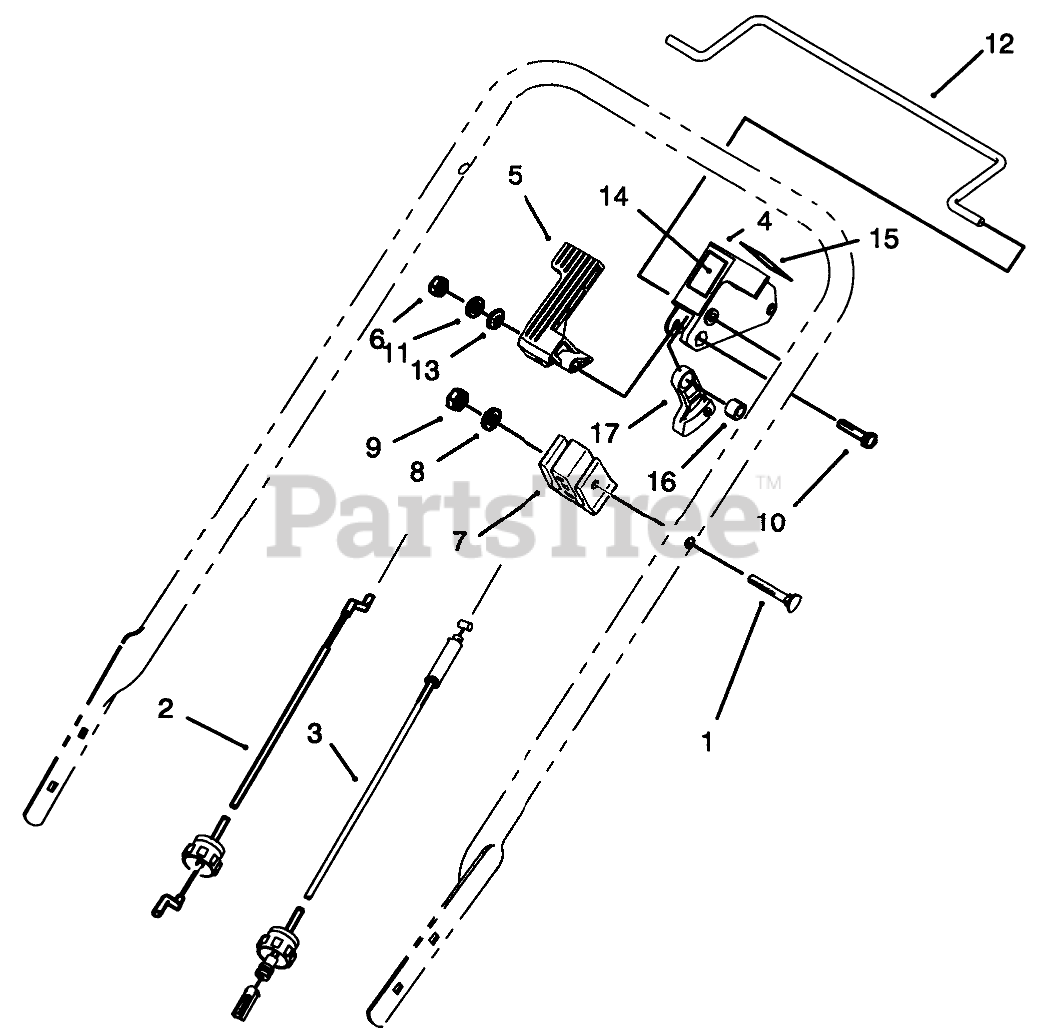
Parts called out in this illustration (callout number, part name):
1	SCREW-HANDLE
2	BRAKE CONTROL
3	CABLE-TRACTION
4	Stop-Pivot
5	LEVER - SHIFT
6	NUT-LOCK, NI
7	SUPPORT-CABLE
8	WASHER-FLAT
9	NUT-LOCK, NI
10	SHOULDER BOLT
11	WASHER-PLAIN
12	Bar-Control
13	WASHER - SPRING
14	DECAL - INSTRUCTION
15	DECAL - INSTRUCTION
16	SPACER-LEVER, TRACTION
17	LEVER-TRACTION
